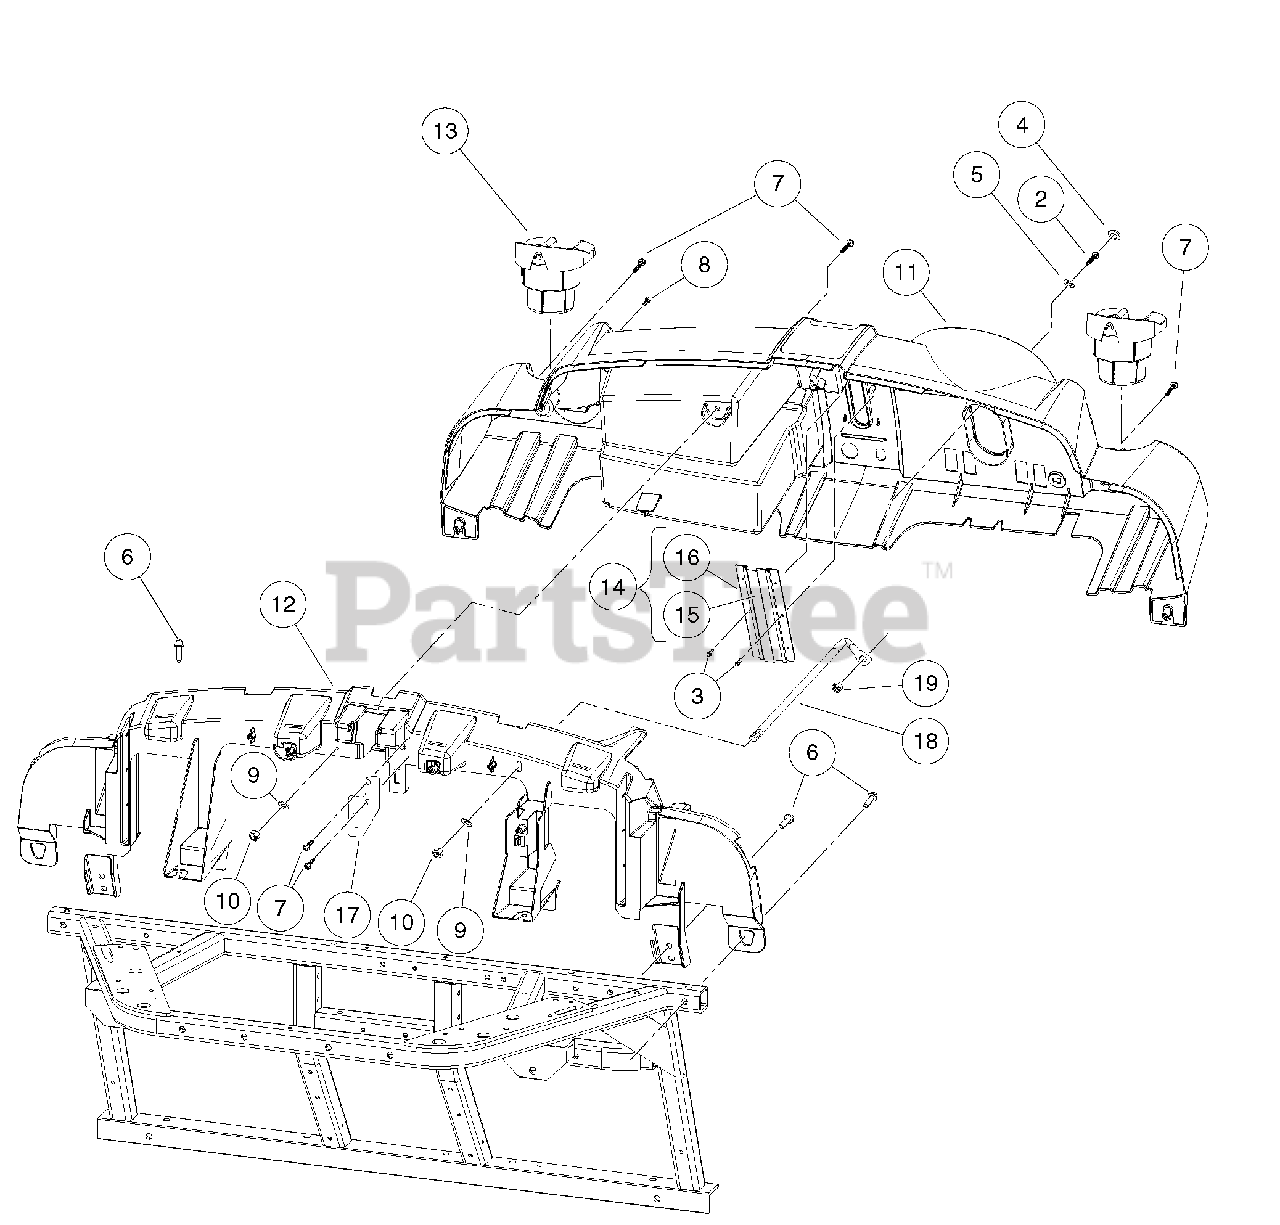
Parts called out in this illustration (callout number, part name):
1	Instl, Dash
2	Screw, 1/4-20 X 1.50 Hex-Head Cap
3	Screw, #8 X 0.500, Hex-Head Hi-Lo
4	Cap, 1/4" Plastic Screw Head
5	Washer, 1/4 Id Scalloped Plast
6	Screw, M8X1.25X30, Hex
7	Screw,m6,torx,interlock,thread
8	M8-1.25 X 80 Sems
9	Washer Hard,m10
10	Lock Nut, Flg M8 X 1.25 Nylon
11	Dash, Design A
12	Support, Structural
13	Cup Holder, Utility
14	Asm, Brush, Fnr
15	Brush, Strip, FNR
16	Holder, Brush, Strip, Fnr
17	Bracket, Hood Support
18	Rod, Connection, Dash
19	Locknut, 1/4-20 Nylon Insert
